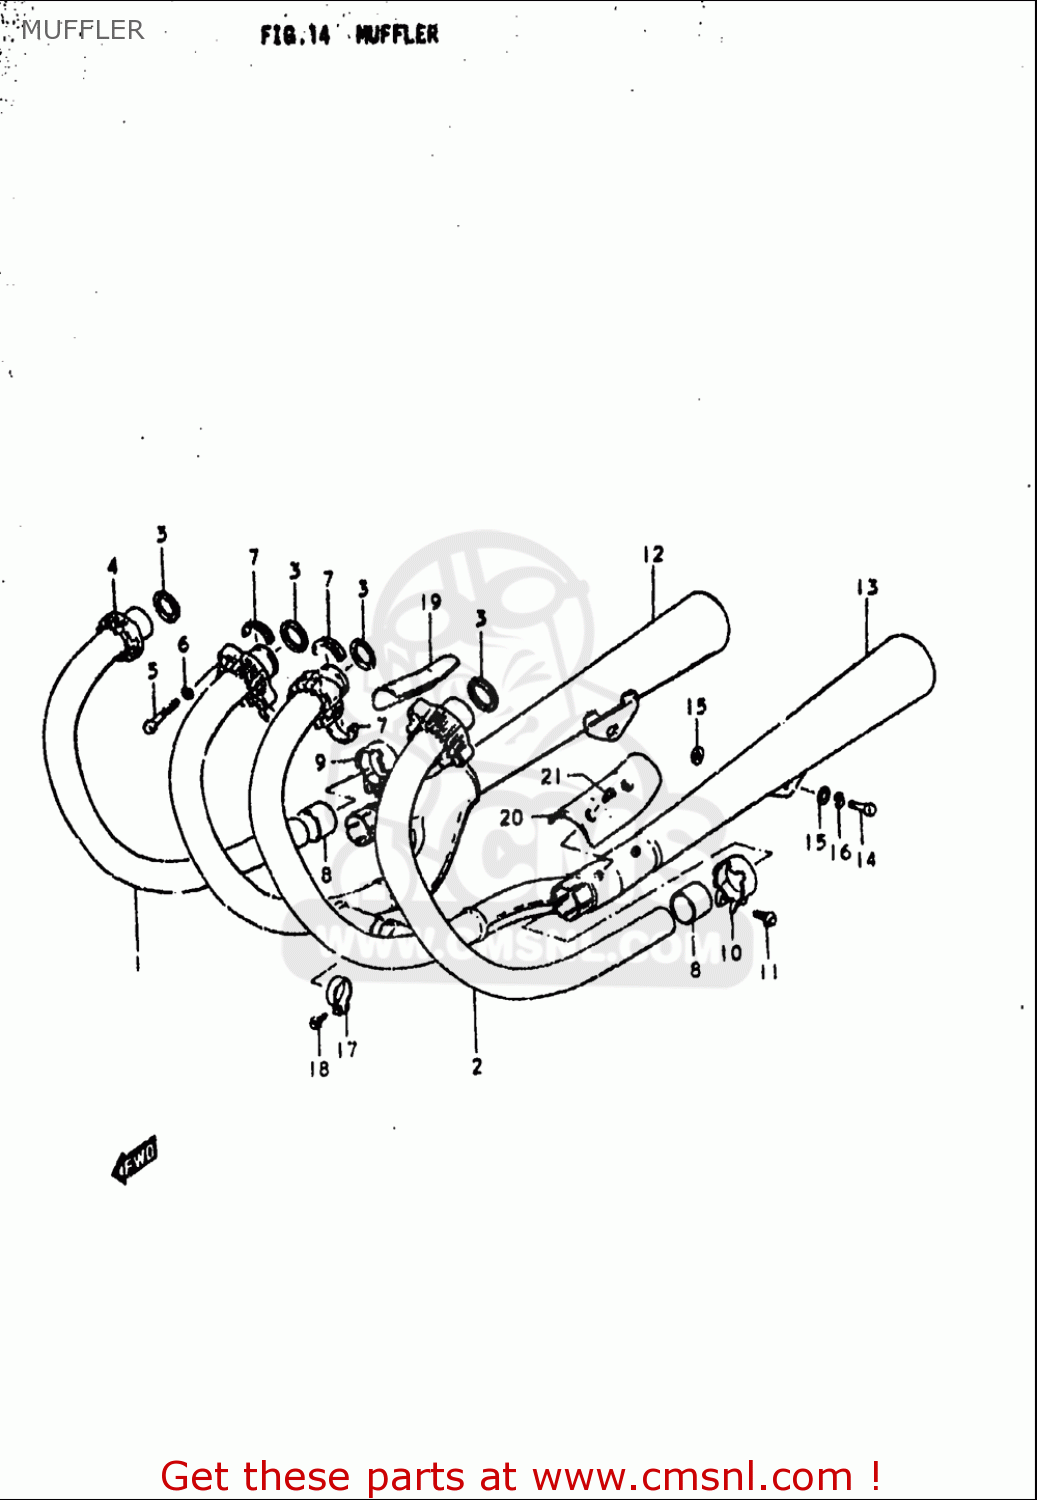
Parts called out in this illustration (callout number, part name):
1	PIPE,EXHAUST,R
2	PIPE,EXHAUST,L
3	GASKET,EXHAUST PIPE (NAS)
4	CLAMP,EXHAUST PIPE
5	BOLT
6	WASHER,LOCK
7	PLATE,EXHAUST P
8	CONNECTOR,MUFFLER
9	CLAMP,MUFFLER CONNECTOR,R
10	CLAMP,MUFFLER CONNECTOR,L
11	BOLT
14	BOLT
15	WASHER
16	WASHER,LOCK
17	CLAMP
18	BOLT
21	SCREW(5X6)
